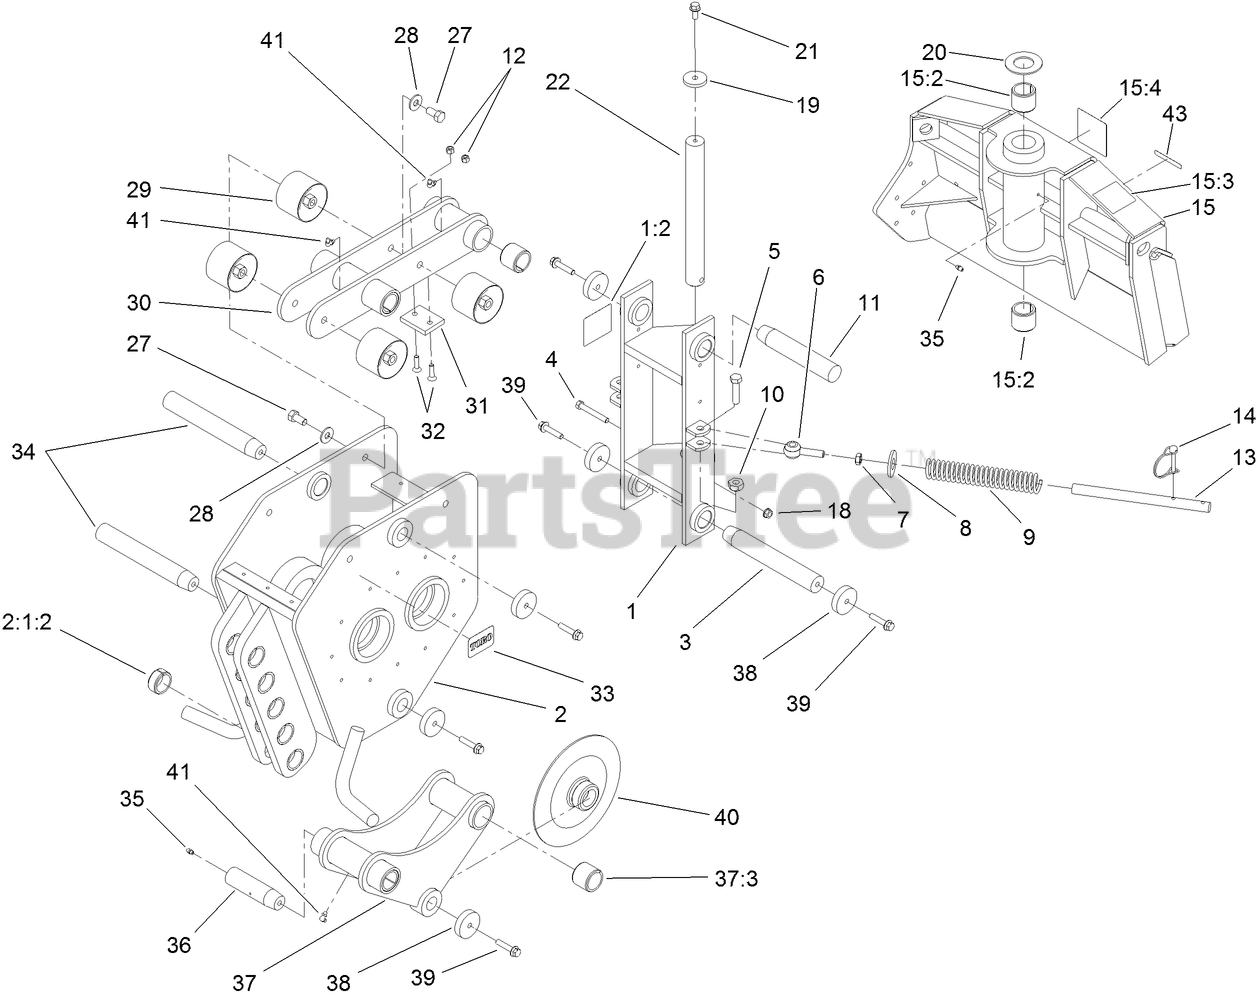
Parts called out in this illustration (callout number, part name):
1	CLEVIS ASM
1:2	DECAL-WARNING
2	FRAME ASM
2:1:2	BUSHING-TENSION
3	PIN-TAPERED
4	SCREW-HH
5	SCREW-HH
6	ROD END
7	NUT-JAM
8	WASHER
10	NUT-HEX
11	PIN-TAPERED
12	NUT-LOCK, NI
13	ROD-THREADED
14	PIN-HITCH
15	QTACH ASM
15:2	BUSHING-TENSION
15:3	DECAL-DANGER
15:4	DECAL
18	NUT-HHF, WHIZ
19	WASHER-PLAIN
20	WASHER
21	SCREW-HHF
27	SCREW-HH
28	WASHER-FLAT
29	MOUNT-SANDWICH
30	LINK ASM
31	PAD-STOP
32	SCREW-FH
33	DECAL
34	PIN-TAPERED
35	FITTING-GREASE
36	PIN-TAPERED
37	LINK ASM
37:3	BUSHING-TENSION
38	WASHER-CLUTCH
39	SCREW-HHF
40	COULTER
41	FITTING-GREASE, 90 DEG
43	DECAL-WARNING
